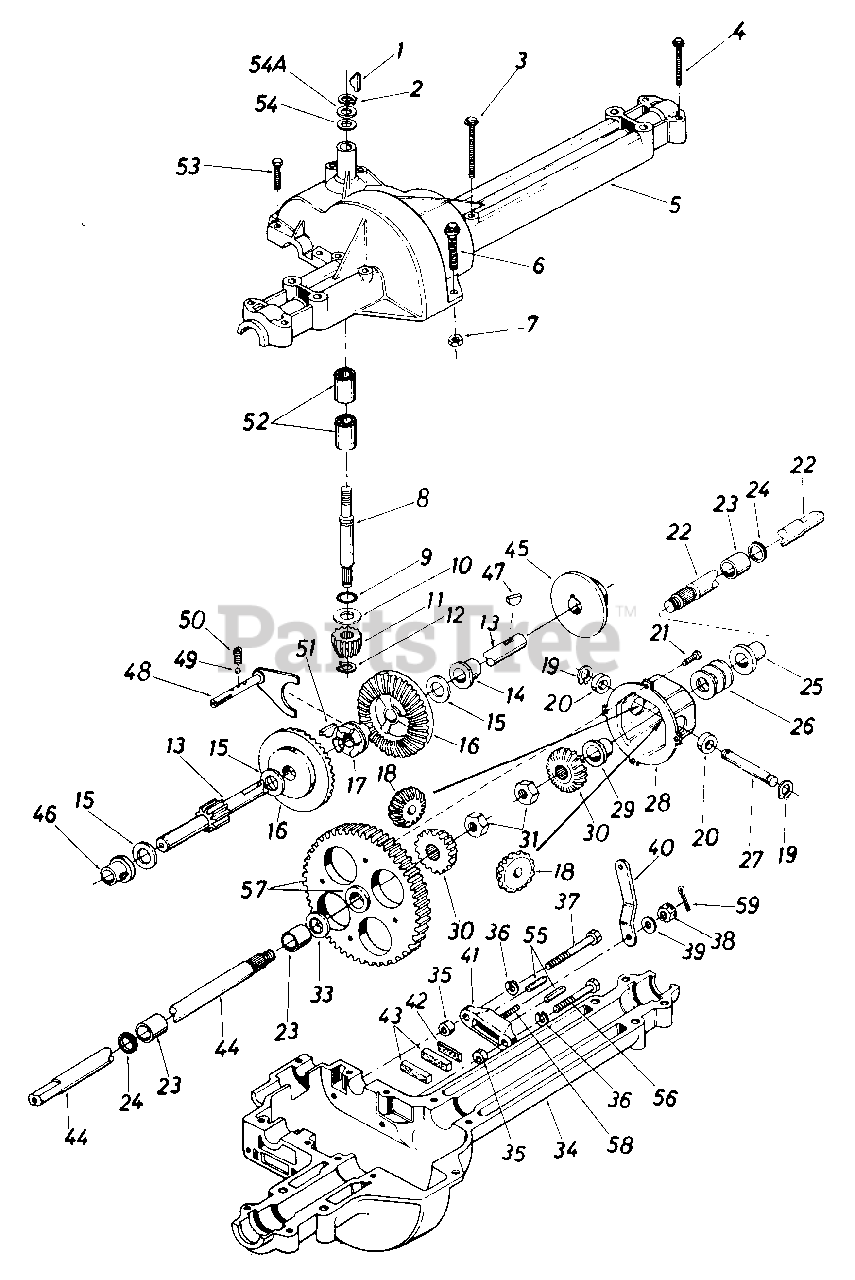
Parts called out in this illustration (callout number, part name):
1	#4 Hi-Pro Key 8/32 x 5/8 Dia.
2	Snap Ring .625 Shaft
3	Hex Bolt 1/4-20 x 1.75 Lg*
4	Hex Bolt 1/4-20 x 1.25 Lg*
5	Upper Housing
6	Hex Fl-Bolt 1/4-20 x .88 Lg*
7	Hex Nut 1/4-20 Thd*
8	Input Shaft
9	Square Seal 5/8 I.D.
10	Thrust Washer 5/8 I.D. x 1.25 O.D.
11	Pinion Input 14T
12	Retaining Ring 7/16 Ext.
13	Drive Shaft R.H.
14	Flange Brg. 5/8 I.D. x 3/4 Lg. *
15	Fl-Wash.
16	Bevel Gear 42T
17	Clutch Collar
18	Miter Gear 15T
19	Snap Ring
20	Thrust Bearing 1/2 I.D. x 1.0" O.D.
21	Pan Head Scr. 1/4-20 x .50 0 Lg. w/ Patch
23	Sleeve Bearing 3/4 0 I.D. x 1.0" Lg.
24	Oil Seal 3/4 I.D.
25	Flange Bearing 3/4 I.D. x 1 5/1 6 Lg.
26	Fl-Wash. .760 I.D. x 1. O.D.
27	Cross Shaft
28	Differential Housing Ass'y.
30	Miter Gear
31	Hex Ins. L-Nut 1/2-20 Thd.
33	Fl-Wash. .760" I.D. x 1.49" O.D.
34	Lower Housing
35	Spacer .53" O.D. x 3/8" Lg.
36	L-Wash. 1/4" I.D*
37	Hex Bolt 1/4-20 x 1.50" Lg. (Grade 5)
38	Castle Nut 5/16-24 Thd*
39	Fl-Wash. .344" I.D. x .875" O.D.
40	Actuating Arm R.H.
42	Puck Plate
43	Brake Puck
46	Flange Bearing 5/8" I.D. x 15/16" Lg.
47	Woodruff Key 3/16 x 5/8 HT
48	Shift Fork Ass'y.
49	Ball Detent .250" Dia.
50	Spring Detent
51	#9 Hi-Pro Key 3/16" x 3/4" Dia. HT
52	Needle Brg. 5/8" I.D. x 1/2" Lg.
53	Hex Bolt 1/4-20 x 1.00" Lg.
54	Fl-Wash. 5/8" I.D. x .030
54A	Fl-Wash. 5/8" I.D. x .040
55	Actuating Pin 5/16" Dia.
56	Hex Bolt 1/4-20 x 1.50" Lg. (Grade 5)
57	Differential Gear 72T Ass'y. w/ Bearing
58	Sq. Hd. Bolt 5/16-24 Thd.
59	Cotter Pin 3/32" Dia. x .50" Lg.
